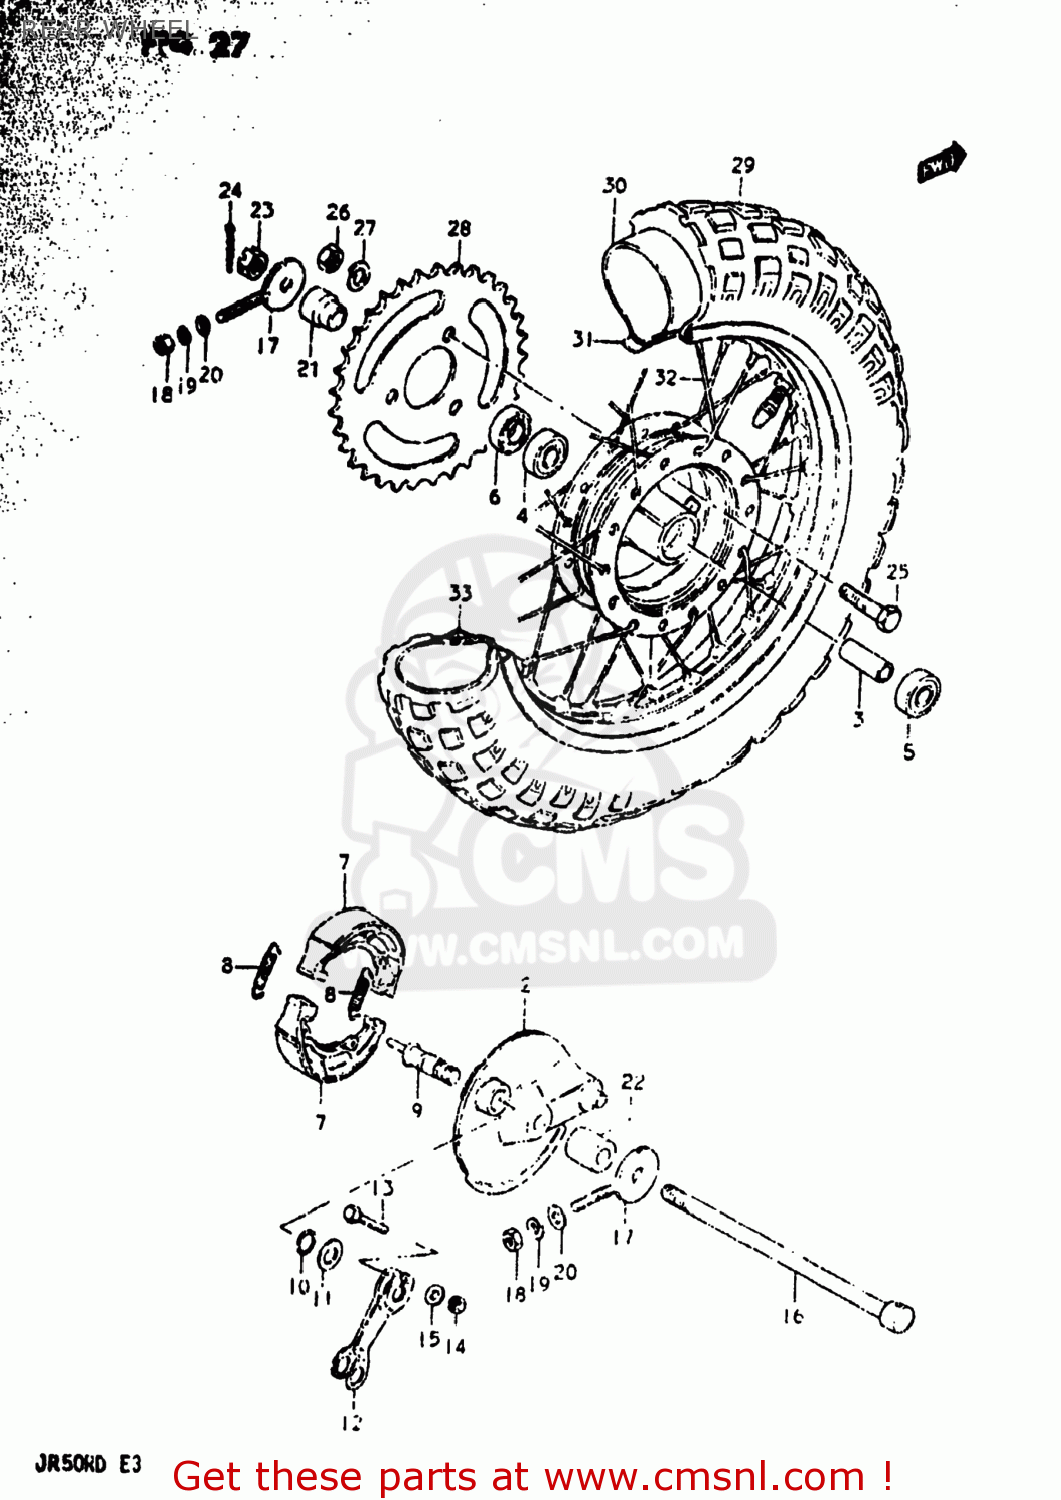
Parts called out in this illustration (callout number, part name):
1	HUB,RR WHEEL
2	PANEL,RR BRAKE ANCHOR
3	SPACER (10.2X16X55)
4	BALL BEARING K
5	BEARING
6	SEAL,OIL(15X27X6)
7	SHOE,BRAKE
8	SPRING(L:34)
9	CAM,FRONT BRAKE
10	O RING(D:2.4,ID:9.8)
11	WASHER (10.5X18X1)
12	LEVER,RR BRAKE CAM
13	BOLT
14	NUT
15	WASHER
16	AXLE,RR
17	ADJUSTER,CHAIN
18	NUT
19	LOCK WASHER
20	WASHER
21	SPACER,RR AXLE,L
22	SPACER,RR AXLE,R
23	NUT
24	PIN 20X20
25	BOLT
26	NUT
27	LOCK WASHER
28	SPROCKET,RR
29	TIRE
30	TUBE,INNER
31	PROTECTOR,INNER TUBE
32	SPOKE SET,RR
33	RIM,WHEEL
